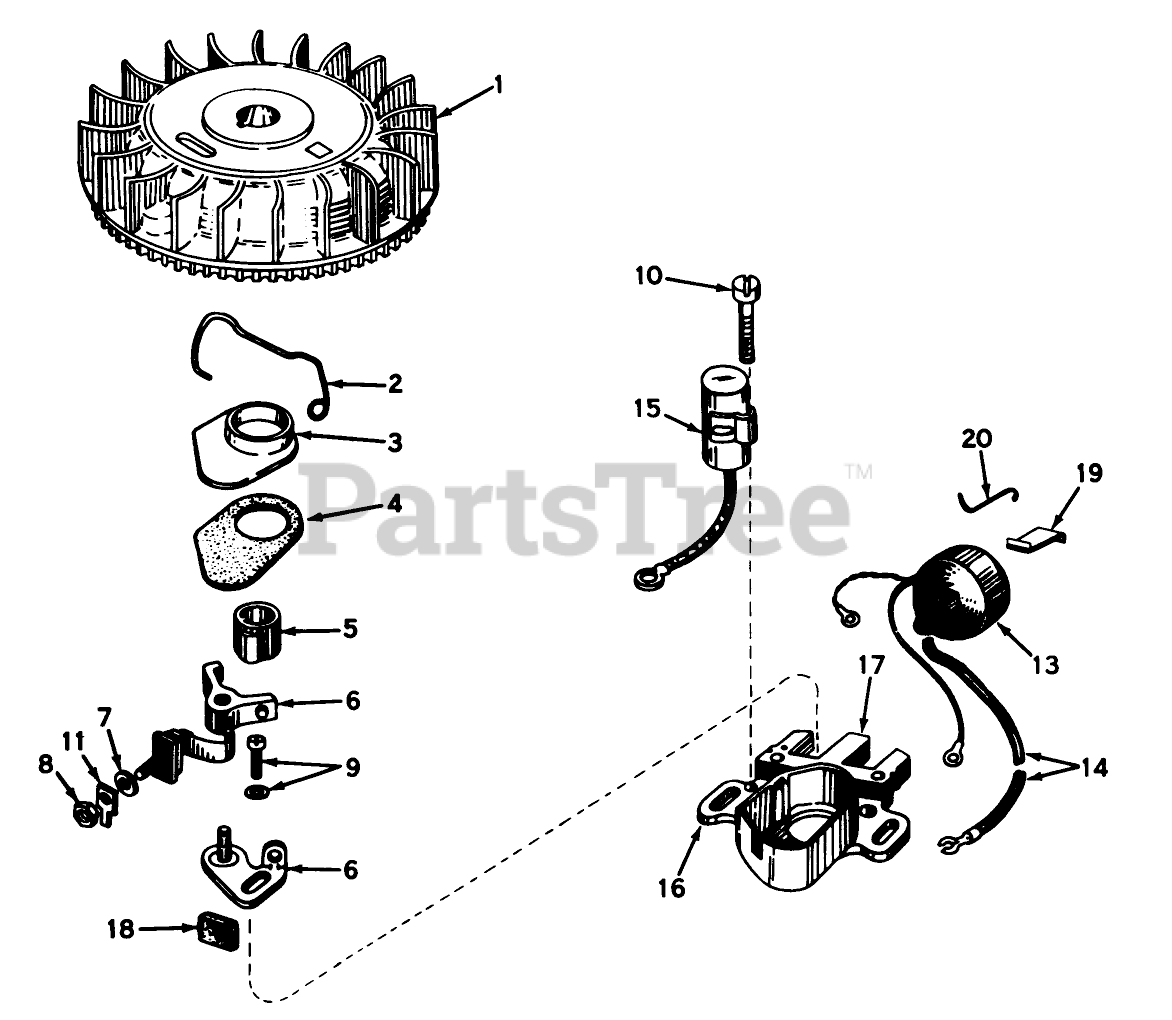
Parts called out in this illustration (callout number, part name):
1	FIywheel
2	Spring Breaker Box
3	Cover, Dust
4	Gasket Dust Cover
5	Cam, Breaker
6	Breaker Assy.
7	Washer
8	DECAL
9	Breaker Screw
10	Condenser Screw
11	Terminal, Ground
13	Coil Assy. (Incl. No. 12)
14	Wire, Lead
15	Condenser
16	Core Plate
17	Stator Assy., (Incl. Nos. 2, 3, 5 thru 14 16 thru 19)
18	Felt,Cam Wiper
19	Spring Coil Wedge
20	Clip, Coil
